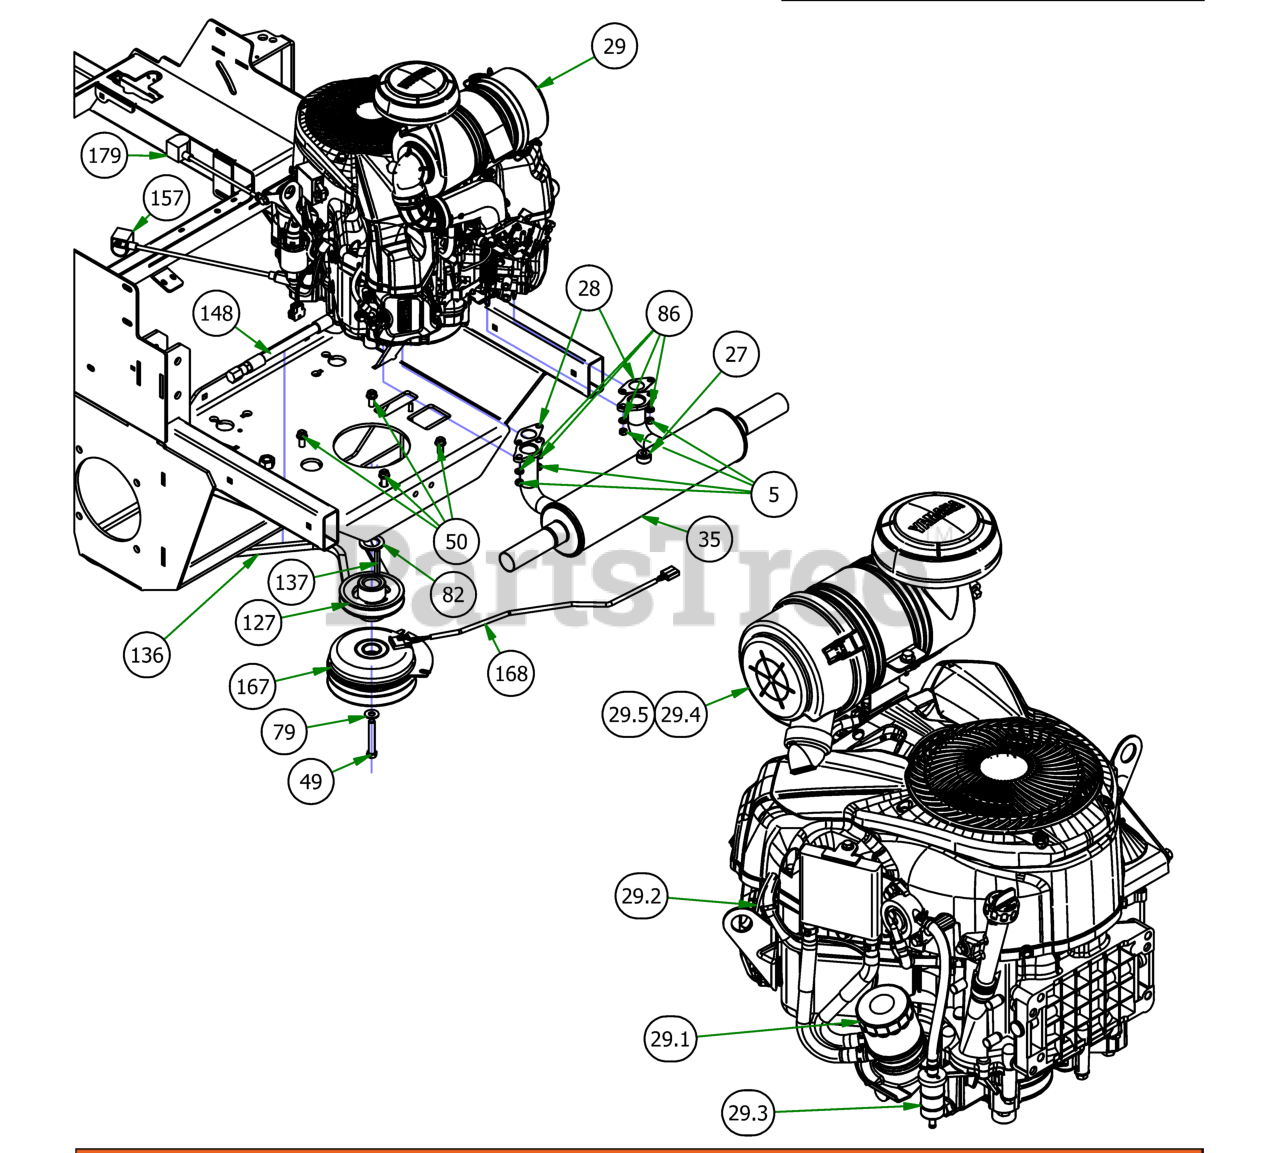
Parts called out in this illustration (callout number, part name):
5	M8-1.25 Zinc Nut
10	3/8-16 HEX SERRATED FLANGE NUT HARD/ZINC
27	O2 Sensor Plug
28	Exhaust Gasket for yamaha
29	Carbureted 27.5hp Yamaha Engine
29.1	Oil Filter
29.2	Yamaha Spark Plug
29.3	Yamaha Fuel Filter
29.4	Canister Air Filter- Outer
29.5	Canister Air Filter- Inner
35	Muffler for 27Hp Yamaha
49	7/16-20 x 2 3/4 Hex C/S GR 8 Yellow Zinc
50	3/8 x 1 1/8 bolt
72	3/8-16 X 1-1/2 HEX CAP SCREW (GR.5) ZINC
79	3/8 FLAT WASHER USS (1" OD) ZINC
82	1 1/8" Flat Spacer
86	5/16" Lock Washer
127	4 3/4 Motor Pulley
136	2019 Rebel Pump Belt
137	1/4 x 2 Square key Stock
148	Oil drain Hose for Yamaha
157	14" Red Battery Cable-Base Outlaw
167	Clutch Assembly
168	Clutch Pigtail
169	2019 Rebel Frame - Powdercoated
179	Starter Cable
